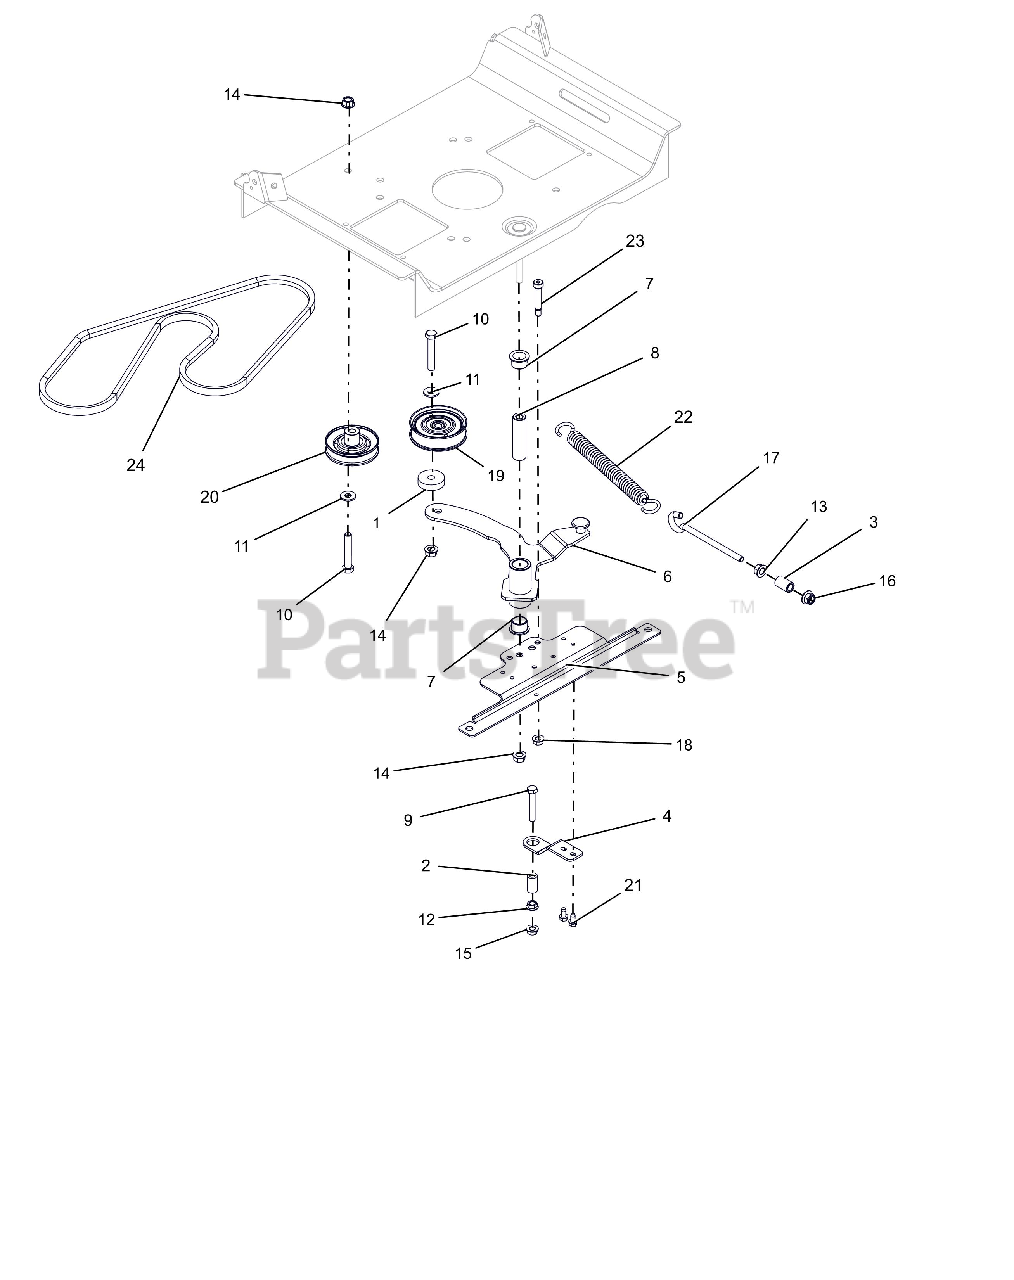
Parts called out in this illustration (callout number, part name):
1	SPACER, .39 X 1.50 X .380
2	SPACER, RUBBER 5/16 IDX1.0 LG
3	SPACER, .375X.625X.970 (PM)
4	BRKT, CLUTCH STOP
5	BRKT, DRIVE IDLER MOUNTING
6	WLDMT,GRD DRIVE IDLER ARM-LGR
7	BSHG-FLG 0.75X0.875X.625X1.125
8	BUSHING, SLEEVE .38X.750X2.78
9	@BLT-HEX .31-18X2.00 GR5 YWZC
10	@BLT-HEX .38-16X2.25 GR5 YWZC
11	@WSHR-FL-STL.38X.875X.083 YWZC
12	@NUT-SPNLK-FLG .312-18 YWZC
13	@NUT-SPNLK-FLG .375-16 YWZC
14	@NUT-LK-TOP-FLG .38-16 YWZC
15	@NUT-LK-TOP-FLG .31-18 YWZC
16	@NUT-LK-NYL-FLG .38-16 YWZC
17	BOLT,.38-16 X 4.25-.62 DIA EYE
18	@NUT-LK-TOP-FLG .31-18 YWZC
19	IDLER, FLAT - 3.05" X .75"
20	ASM, 3.00" V IDLER
21	SCR-TAP .25-20X.50 HWH TR YWZ
22	SPRING, EXTENSION
23	BLT-SHLDR .38X1.5X.31-18 SLT Y
24	V-BELT, A-RAW EDGE
